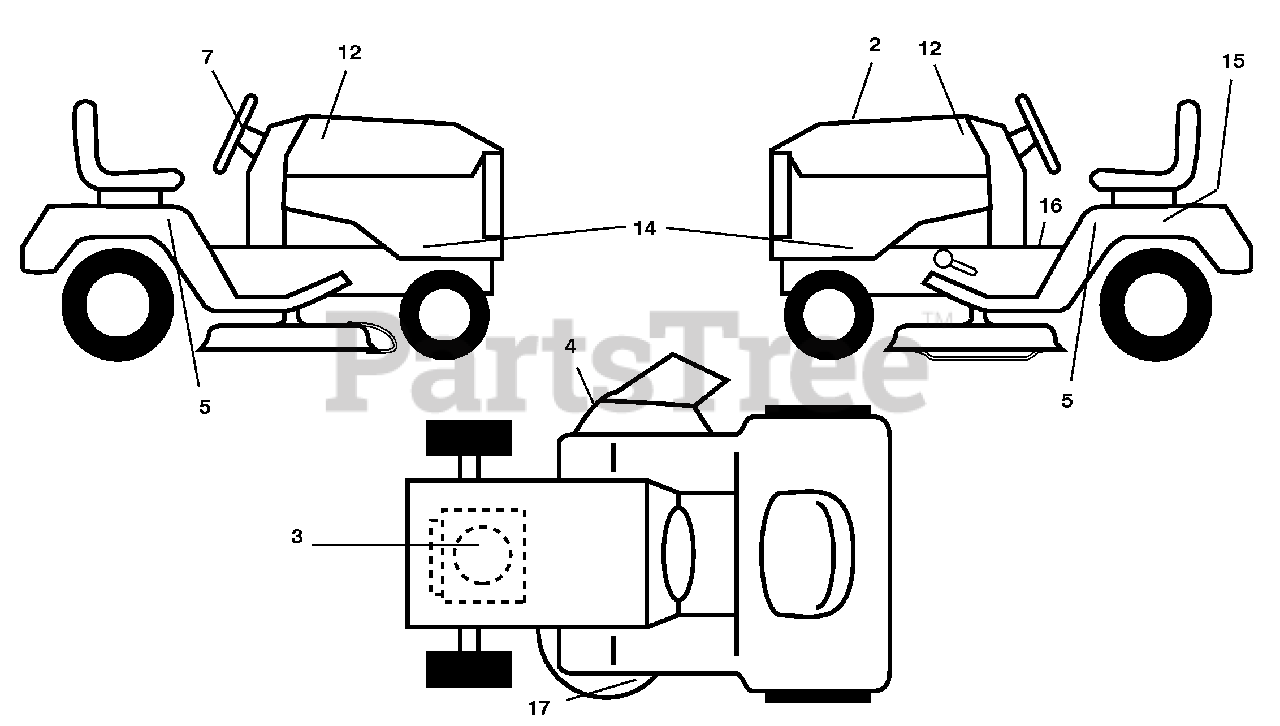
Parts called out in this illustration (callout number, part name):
1	Decal, Fender
2	Decal, Replacement
3	Decal, Engine HP
4	Decal, Warning
5	Decal, Fender Sides
7	Decal, Ins Str Wh
12	Decal, Hood RH/LH
14	Decal, Side PNL
15	Decal, Caution, Battery
16	Decal, Fender Warning
17	Decal, V-Belt Sch.
17	Decal, Handle Lft Height Adj.
17	Pad, Footrest LH
17	Pad, Footrest RH
17	Manual, Operator's E&F
17	Manual, Parts E&F
